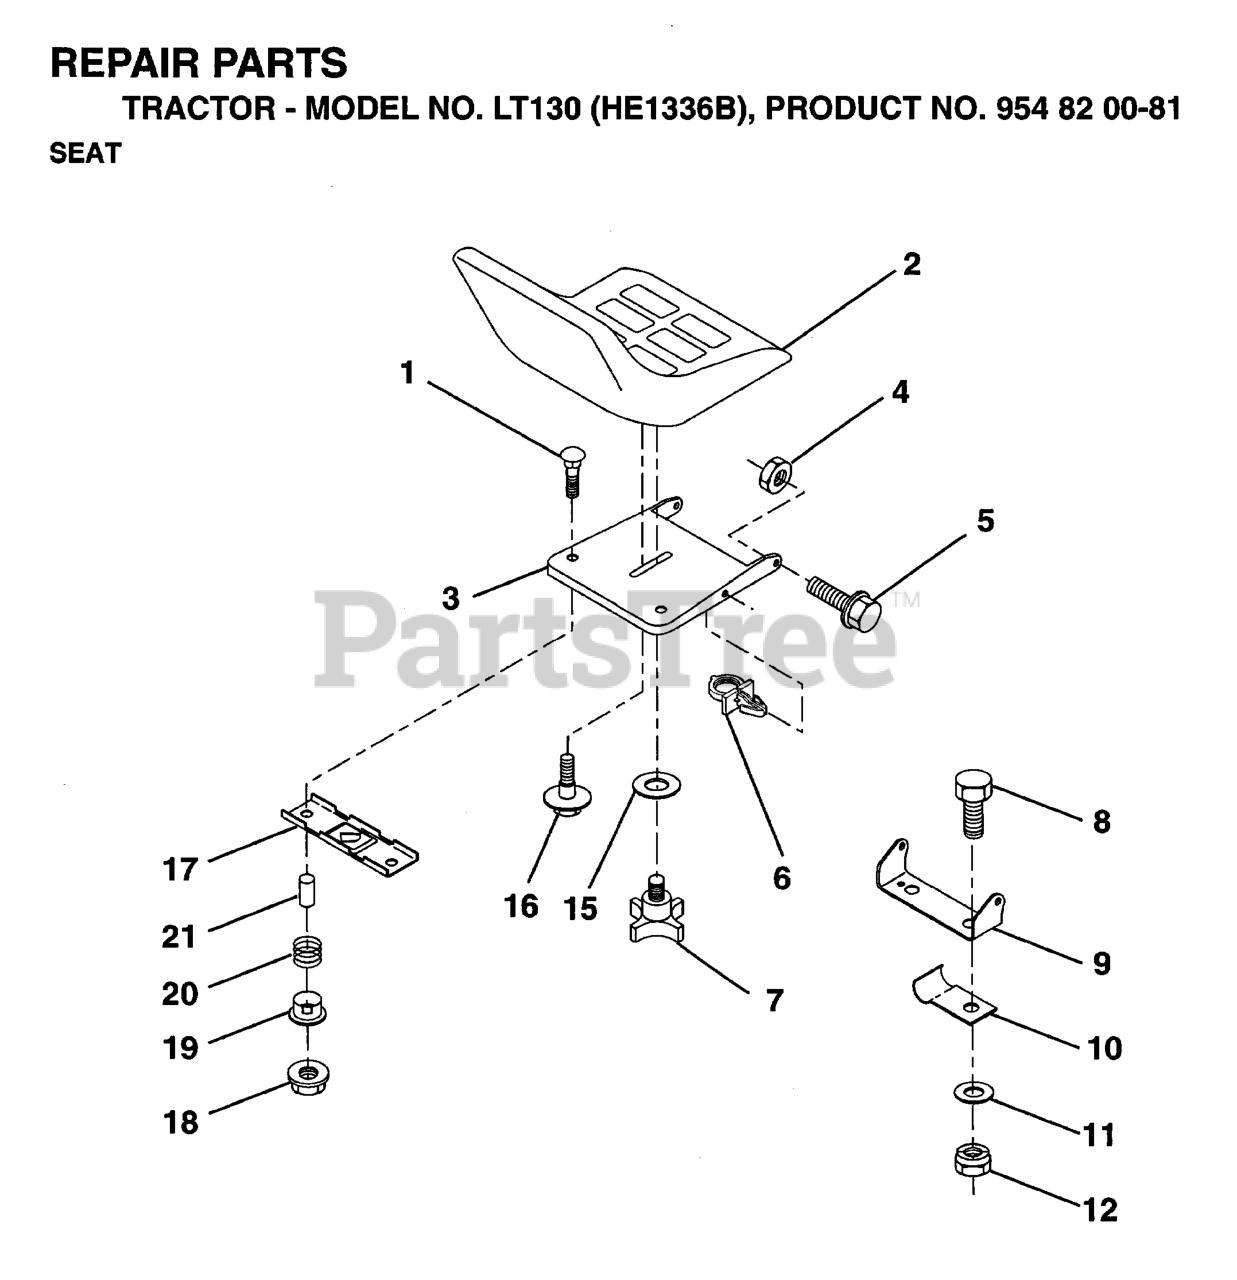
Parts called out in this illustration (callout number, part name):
1	Bolt Rdhd. Sht. Nk 1/4-20 x 1-3/8
2	SEAT
3	SEAT PAN
4	NUT.71038.31-18.HEX.NYLOCK
5	BOLT.SHOULDER.5/16-18
7	KNOB 1/2" YT
8	BOLT
9	SEAT PIVOT BRKT
10	CLIP,INSULATOR
11	WASHER 12/32X2X10GA
12	NUT
16	BOLT,SHOULD
17	BRKT SWITCH
18	NUT T
21	SPACER SPLIT 28X.96
